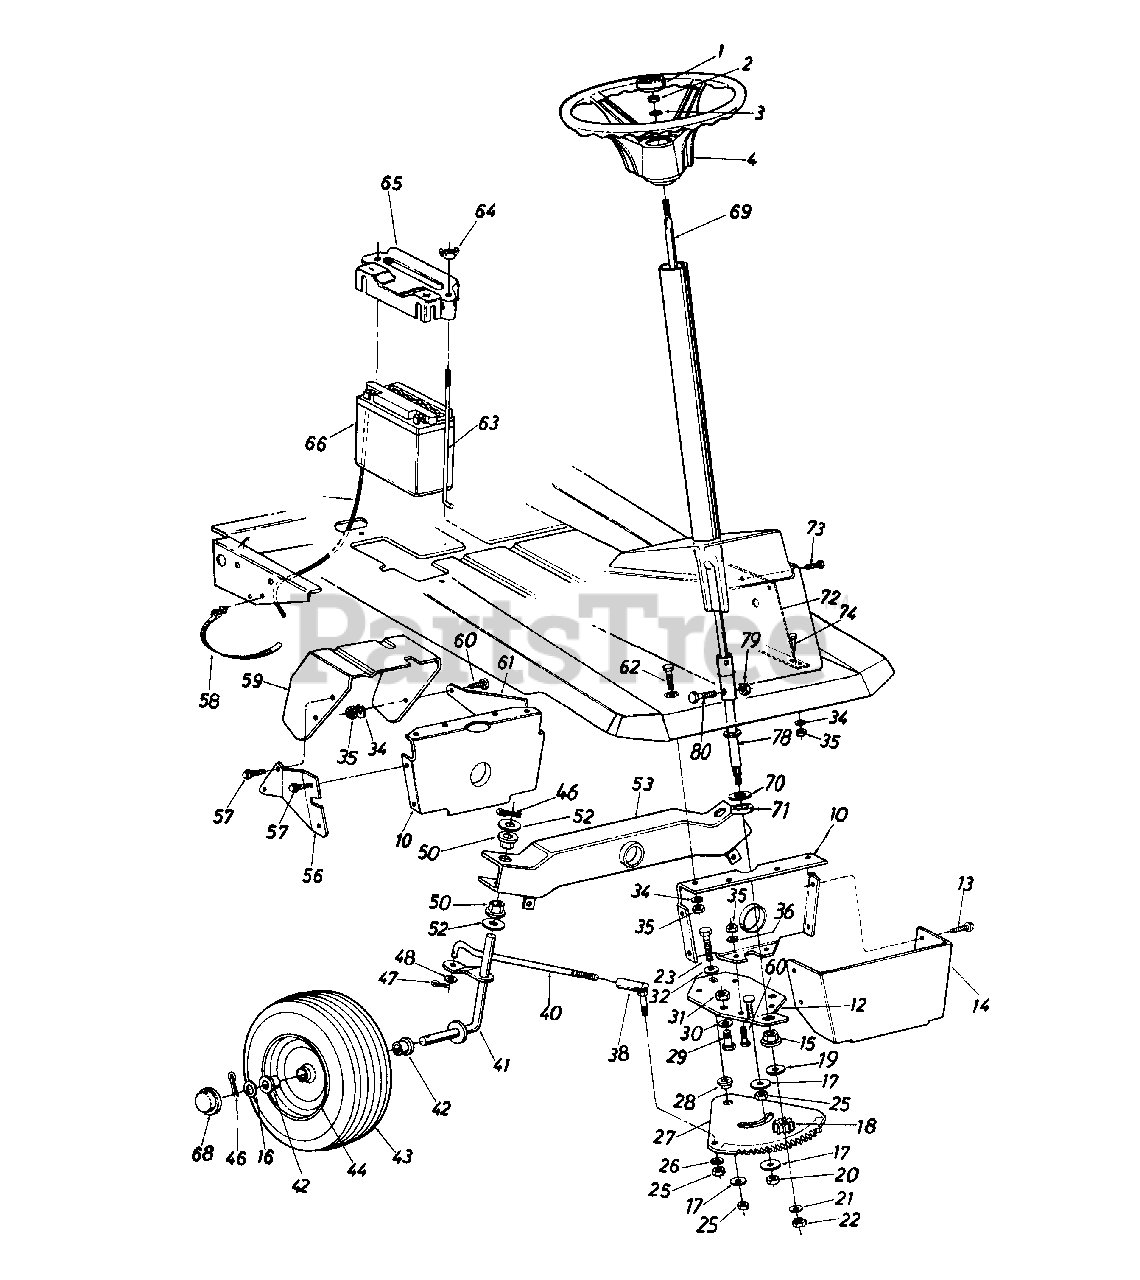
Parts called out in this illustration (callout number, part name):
1	Steering Wheel Cap
2	Hex L-Nut 5/16-24 Thd.
3	Bell-Wash..345" I.D. x .88" O.D
4	Steering Wheel Ass'y.
13	Hex Wash. Hd. AB-Tap Scr. 1/4 x .62" Lg.
16	Fl-Wash..64" I.D. x 1.5" O.D.
17	Fl-Wash. 3/8" I.D. x 1.37" O.D.
18	Steering Pinion Gear
19	Fl-Wash..51" I.D. x 1" O.D.
20	Hex L-Nut 3/8-24
21	Fl-Wash..34" I.D. x .68" O.D.
22	Hex L-Nut 5/16-24 Thd.
23	Hex Bolt 3/8-24 x 1.5" Lg. (Grade 5)
25	Hex Nut 3/8-24 Thd.
26	L-Wash. 3/8" I.D.
27	Steering Gear Segment
28	Shoulder Spacer .622" Dia. x .218
29	Hex Bolt (Nylon) 1/2-13 x .75"
30	Fl-Wash..530" I.D. x .930"
31	Hex Nut 1/2-13 Thd.
32	Bell-Wash..385" I.D. x .88"
34	L-Wash. 5/16" I.D.
35	Hex Nut 5/16-18 Thd.
36	Spr. Wash..32" I.D. x .62" O.D.
38	Ball Joint Ass'y. 3/8-24 Thd.
40	Steering Tie Rod
41	Front Axle Ass'y. - R.H.
41	Front Axle Ass'y.- L.H.
42	Bearing
43	Wheel Assembly Comp.
43	Tire Only
43	Air Valve
43	Grease Fitting
44	Rim Only
46	Cotter Pin 1/8" Dia. x 1.25"
47	Cotter Pin 1/8" Dia. x 1.00"
48	Fl-Wash..385" I.D. x .87"
50	Hex Flange Bearing
52	Fl-Wash..635" I.D. x 1.12"
53	Pivot Bar Ass'y.
58	Cable Tie
59	Clutch-Brake Pedal Ass'y.
60	Hex Bolt 5/16-18 x .75" Lg.
63	Battery Hold Down Rod
64	Wing Nut Solid 1/4-20 Thd.
65	Battery Hold Down Cover
66	12V Battery
68	Hub Cap
69	Steering Shaft Ass'y.
70	Fl-Wash..62" I.D. x 1.25" O.D.
71	Spacer
74	Hex Bolt 5/16-18 x 2.00" Lg.
78	Steering End Adapter
79	Hex Nylon L-Nut 1/4-20 Thd.
80	Hex Bolt 1/4-20 x 1.31" Lg.
